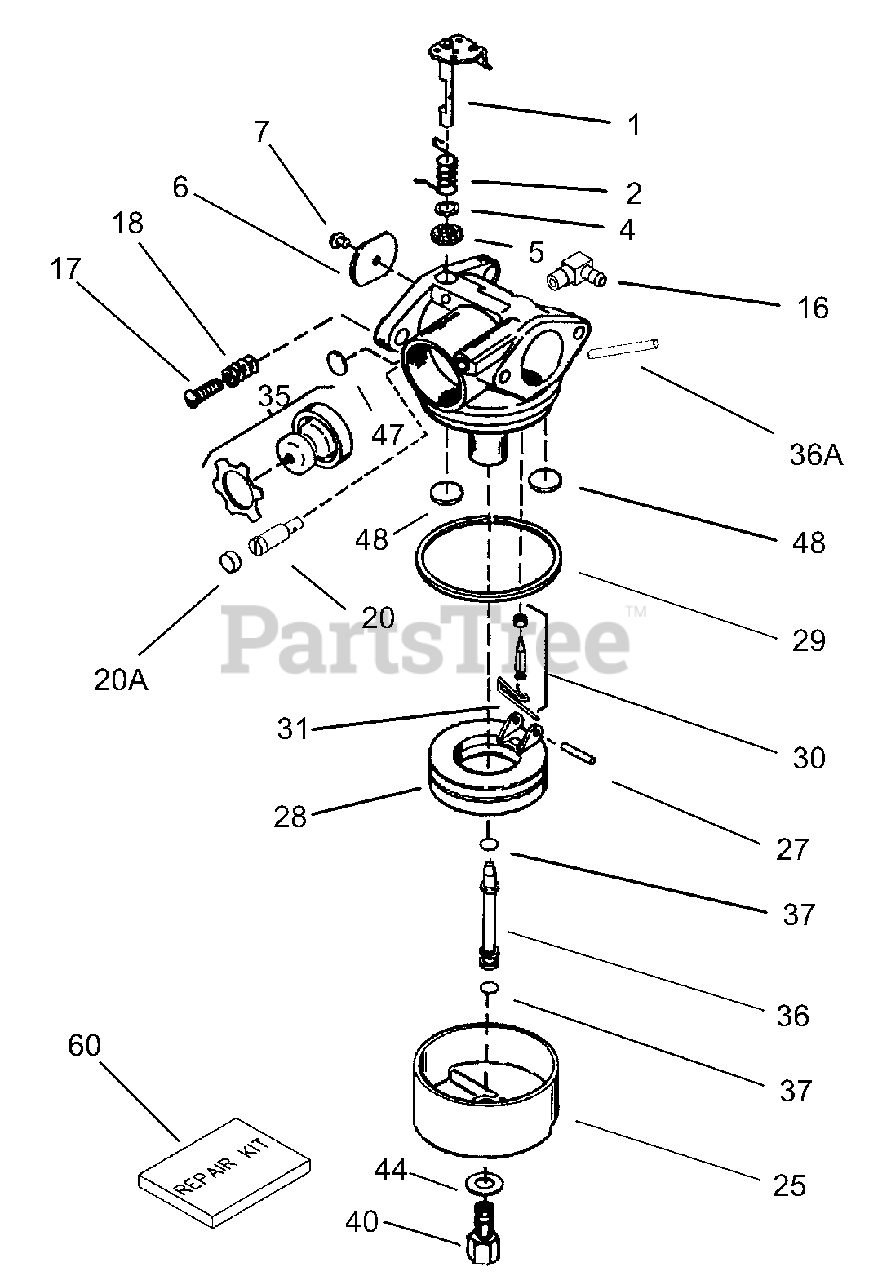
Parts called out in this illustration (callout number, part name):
1	Throttle Shaft and Lever ASM
2	Spring-Return,Throttle
4	Washer-Dust Seal
5	Seal-Dust
6	Shutter-Throttle
7	Screw-Shutter
16	Fitting-Fuel
17	Throttle Crack Screw/Idle Speed Screw
18	Spring-Tension
20	Screw-Idle Restrictor
20A	Cap-Idle Restrictor Screw
25	Bowl-Float
27	Shaft-Float
28	Float (Plastic)
29	O-Ring-Float Bowl
30	Inlet Needle, Seat, and Clip ASM (Incl. Ref. #31)
31	Spring Clip
35	Primer Bulb/Retainer Ring
36	Tube-Main Nozzle
36A	Tube Extension-Bowl Vent
37	O-Ring, Main Nozzle Tube
40	Nut-High Speed Bowl
44	Washer-Bowl Nut
47	Welch Plug-Idle Mixture Well
48	Welch Plug-Atmospheric Vent
60	Repair kit
